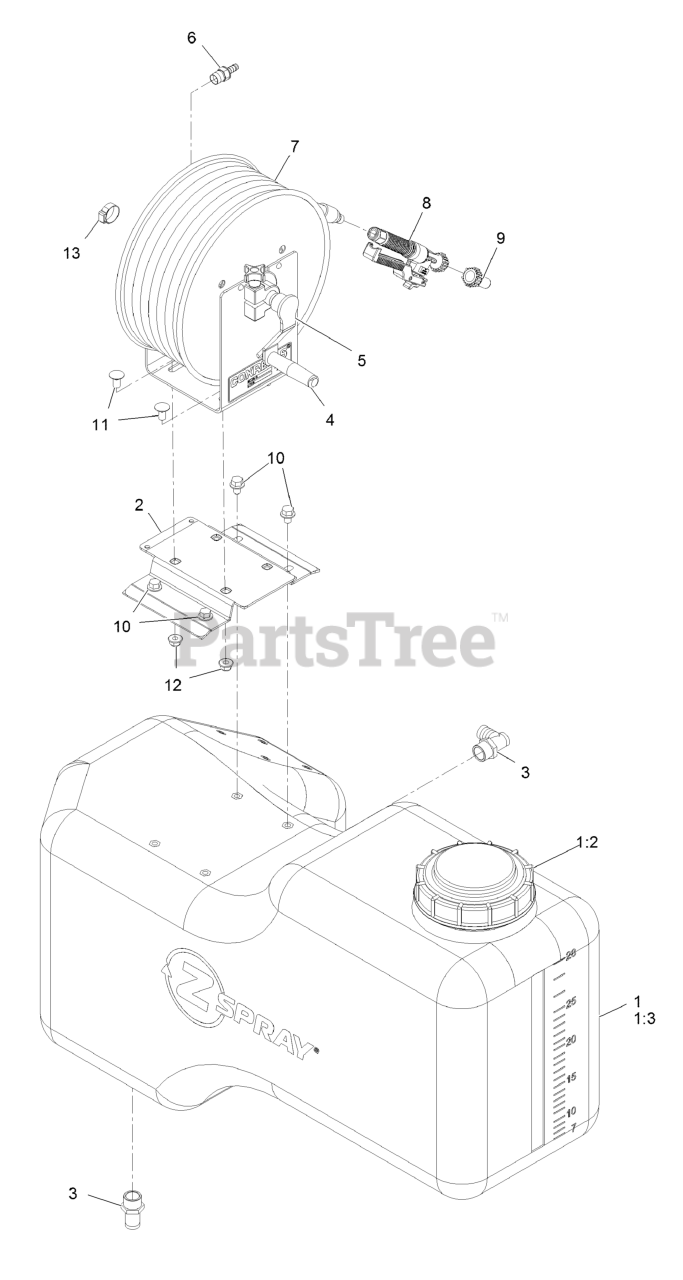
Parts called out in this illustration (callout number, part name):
1	ASM-TANK, LT
1:2	CAP-TANK, SPRAY
1:3	FITTING-BULKHEAD
2	MOUNT-REEL, HOSE
3	FITTING-ELBOW, 90
4	REEL-HOSE
5	Crank-Reel
6	FITTING,MALE
7	HOSE-SPRAY, 75'
8	GUN-SPRAY, SPOT
9	TIP-SPRAY, #12 SPOT
10	Screw-HHF
11	SCREW-CARRIAGE
12	Nut-Hex Flange
13	CLAMP-OETIKER, 167
